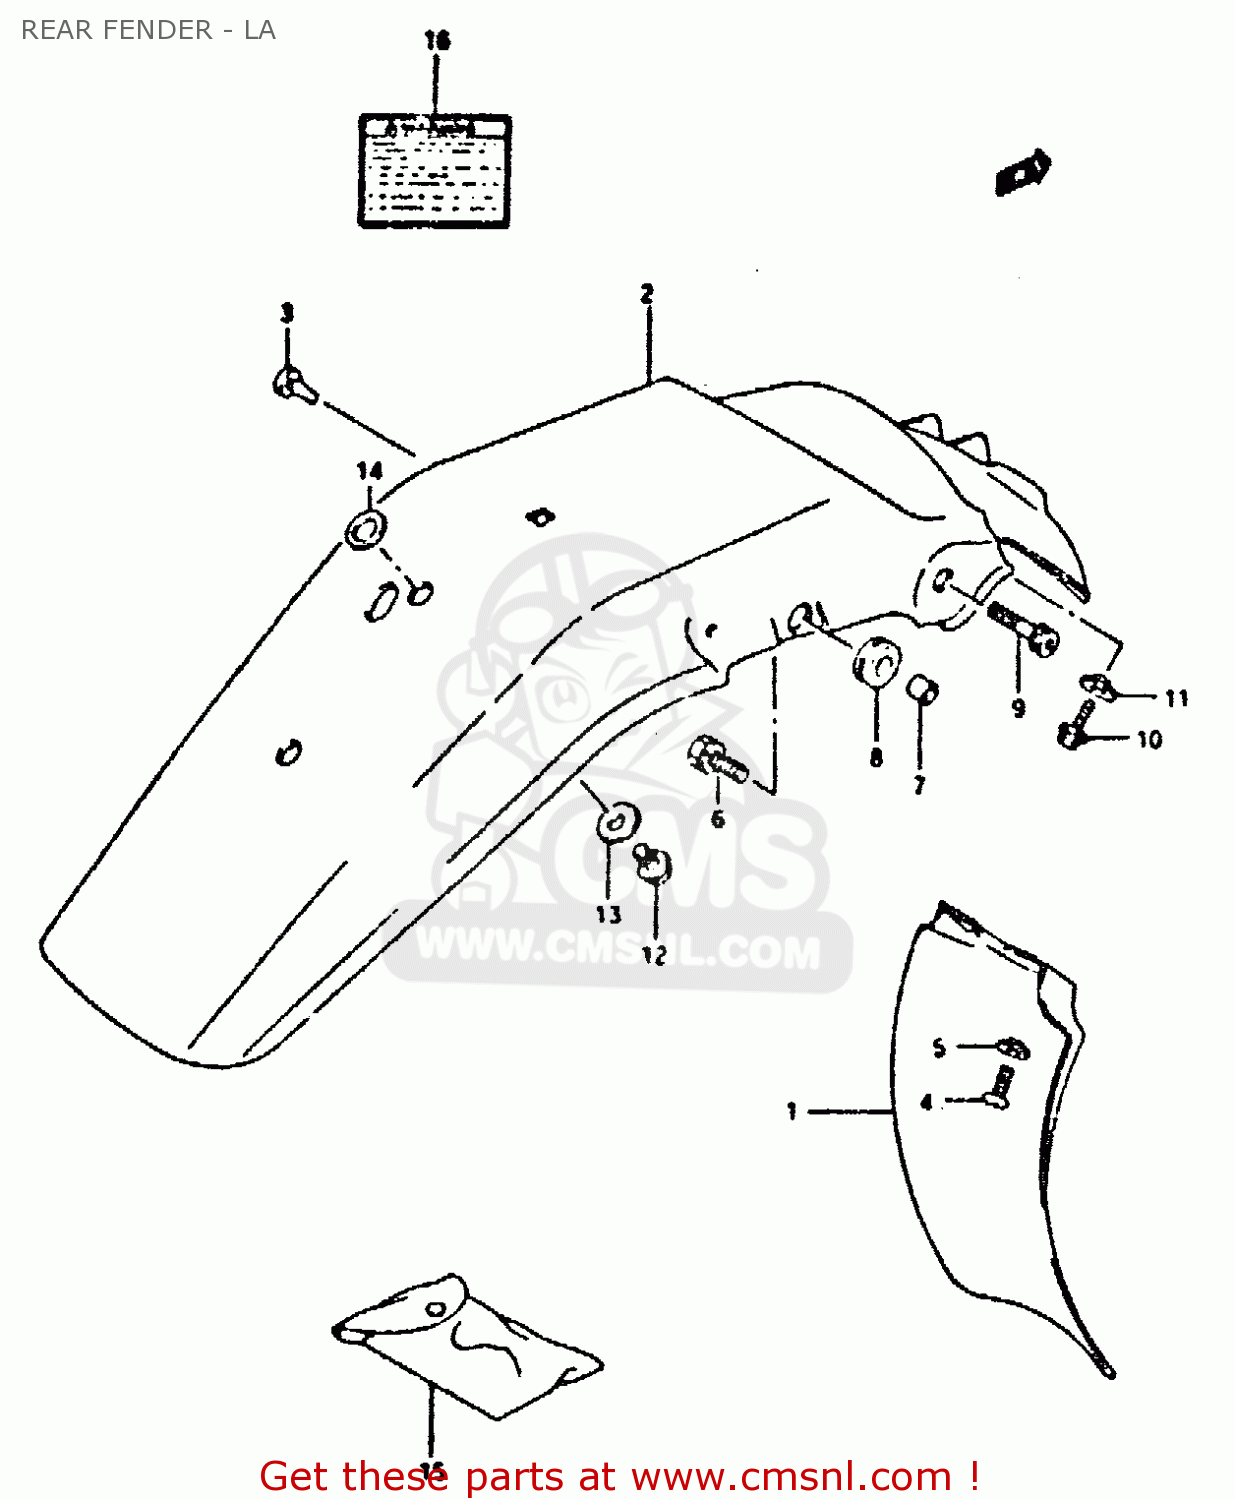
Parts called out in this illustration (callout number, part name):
1	BODY,RR FENDER FR
2	BODY,RR FENDER RR
3	CUSHION,RR FENDER SIDE
4	SCREW 6X12
5	WASHER
6	BOLT
7	SPACER (8.8X12X7)
8	CUSHION
9	BOLT(8X30)
10	BOLT
11	WASHER
12	BOLT, UPPER
13	WASHER
14	WASHER(14.2X26X1.2)
15	TOOL ASSY
16	LABEL
17	MANUAL, OWNERS
